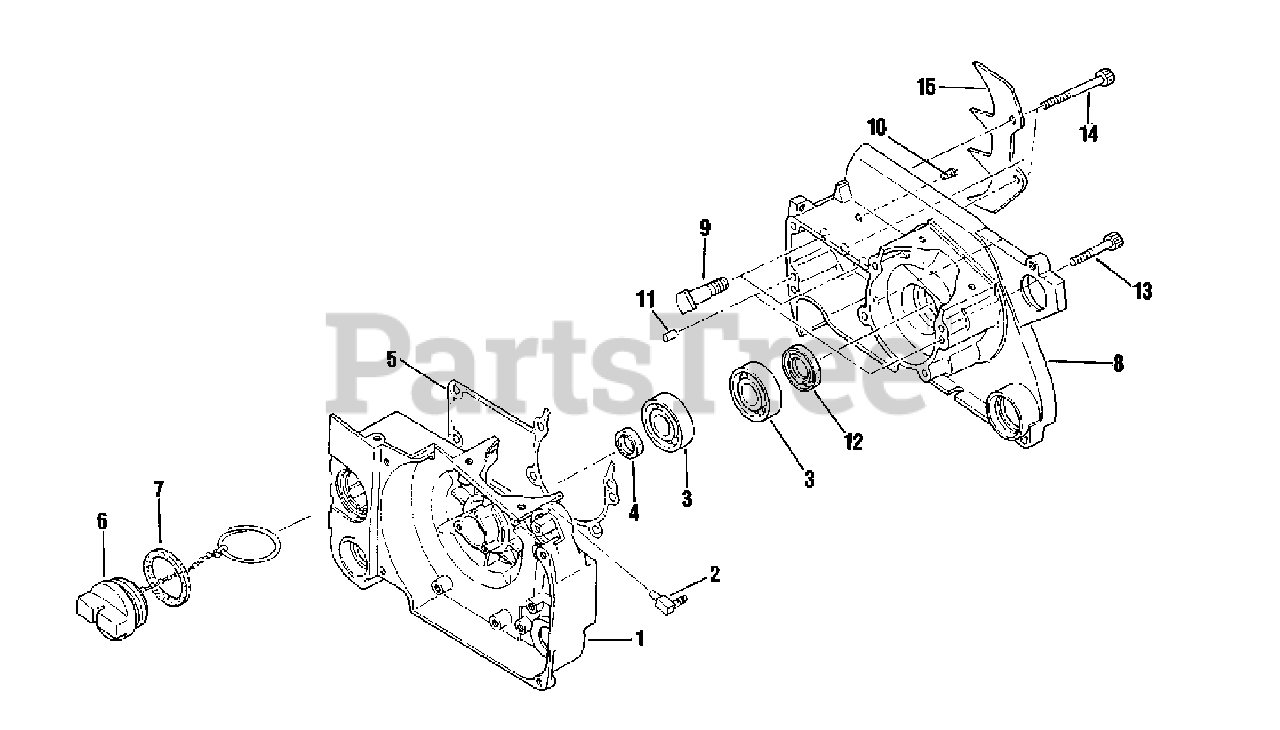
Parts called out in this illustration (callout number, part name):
1	CRANKCASE ASSY
2	CONNECTOR, PIPE
3	BEARING, BALL 6202
3	BEARING, BALL
4	SEAL, OIL 12
5	GASKET, CRANKCASE
6	CAP, OIL
7	GASKET
9	STUD, GUIDE BAR
10	VALVE, CHECK
11	PIN, LOCATING
12	SEAL, OIL 17
13	SCREW - 5×35
14	BOLT M5×50
15	SPIKE
